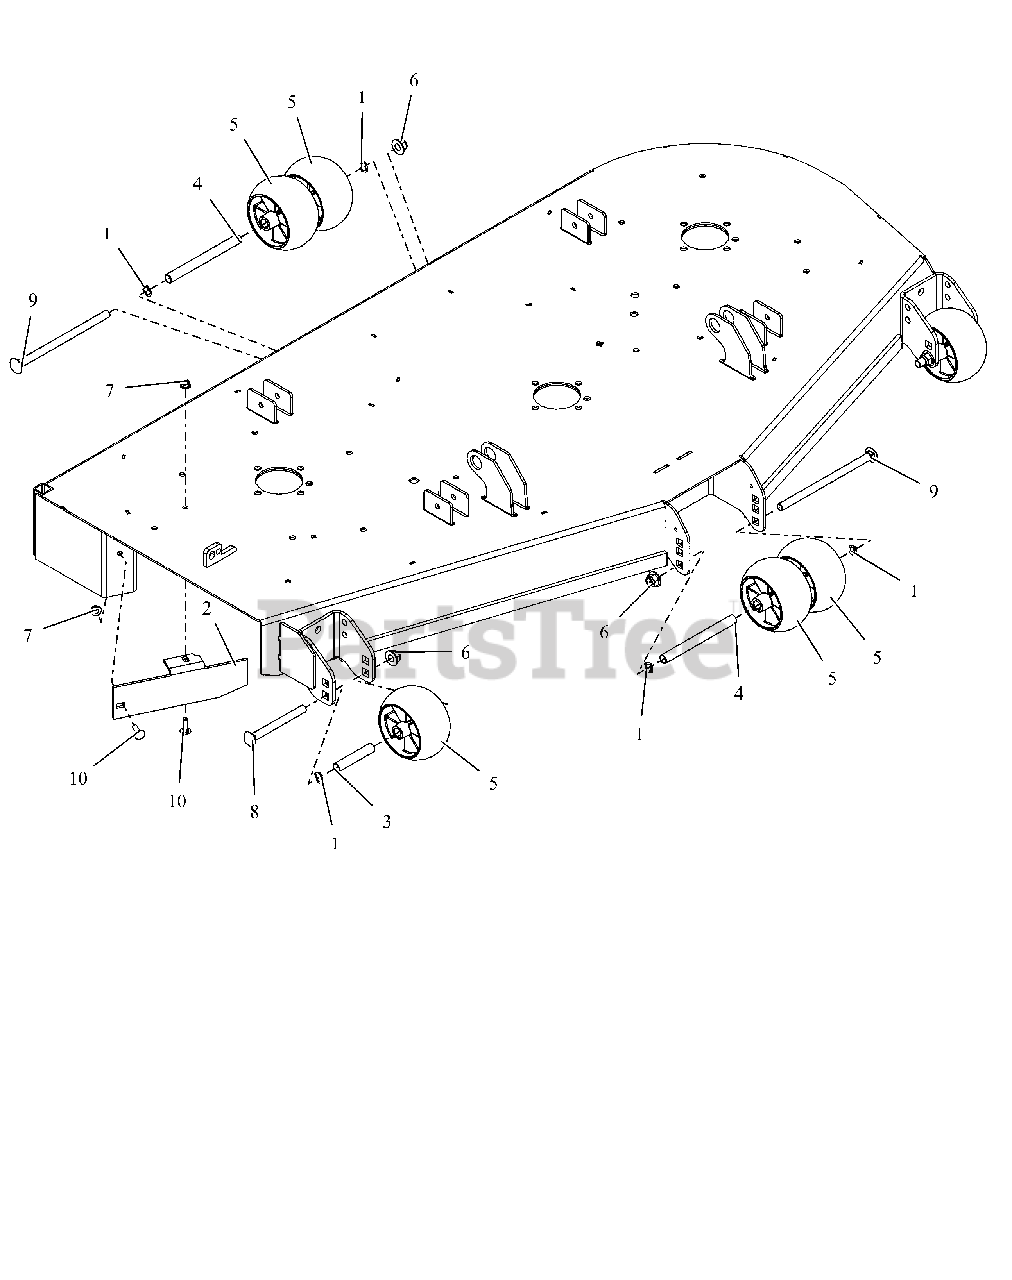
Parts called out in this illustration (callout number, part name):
1	WAVE WASHER .531X.781X.125FH
2	60" DISCHARGE BAFFLE - RED
3	SPACER, .510X.625X3.35
4	SPACER, .510X.625X6.50
5	ANTI-SCALP WHEEL - 5X3 CTR
6	NUT,NYL-FLG .50-13 GF ZCC
7	NUT,NYL-FLG .31-18 GF ZCC
8	BLT, RHSN .50-13X5.00 G5 ZCC
9	BLT, RHSN .50-13X8.50 G5 ZCC
10	BLT,RHSN .31-18X1.00 G5 ZCC
